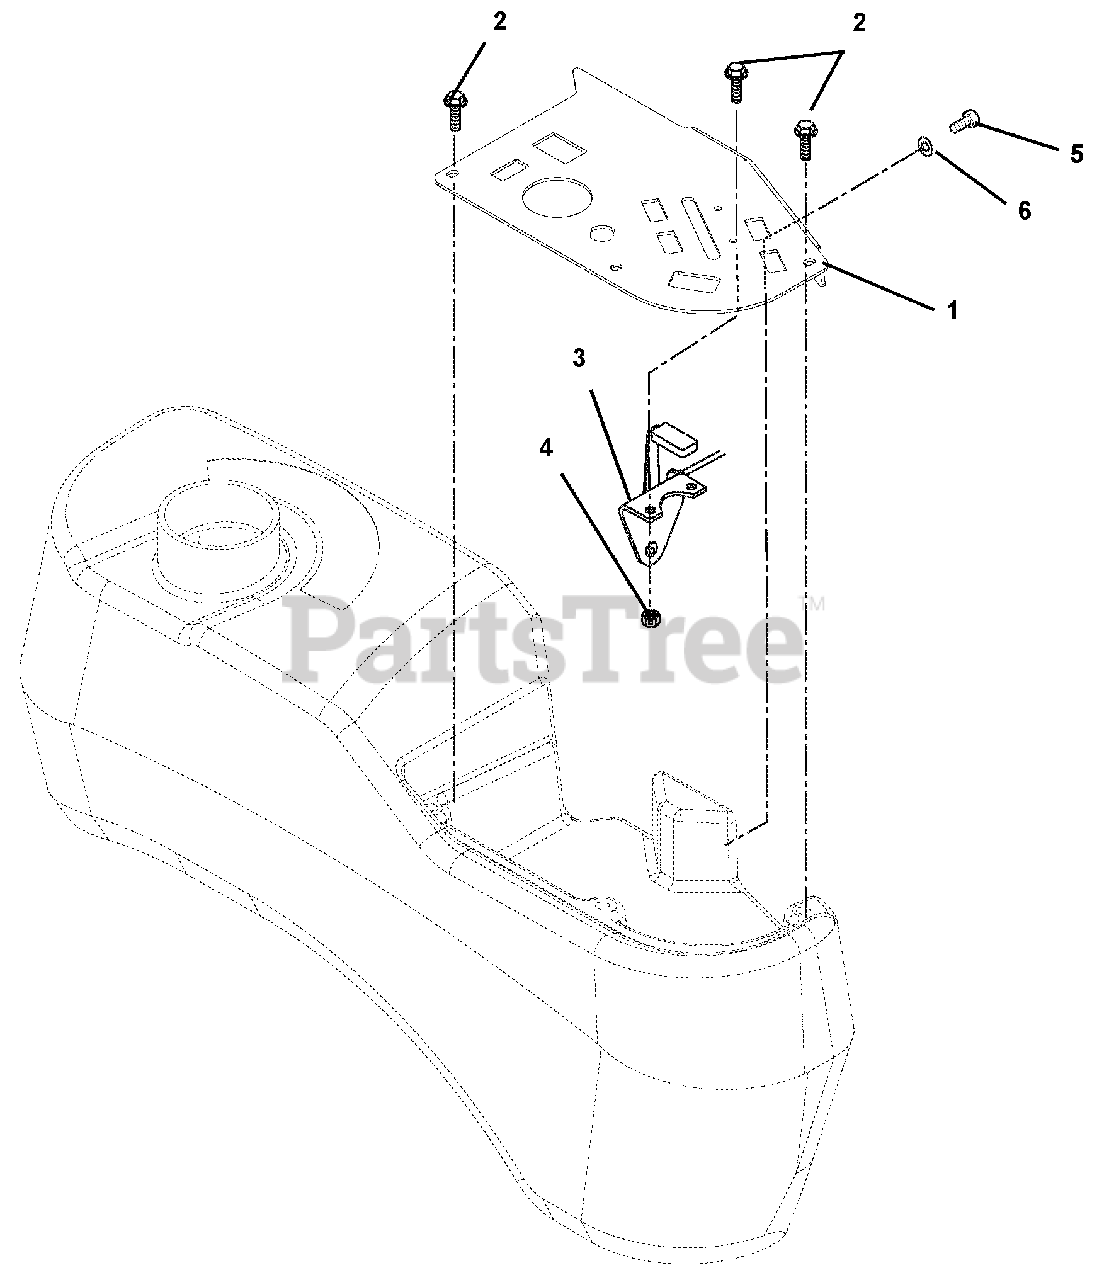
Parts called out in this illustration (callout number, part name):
1	Panel-Control
2	Screw-Machine 10-24 x .50 Hex Washer Head Stainless
3	Throttle, Control
4	Nut-Locking-Nylon 10-24 With Insert
5	Bolt-Hex .31-18 x .75 Grade 5
6	Washer-Flat-Steel .38 x .875 x .083
